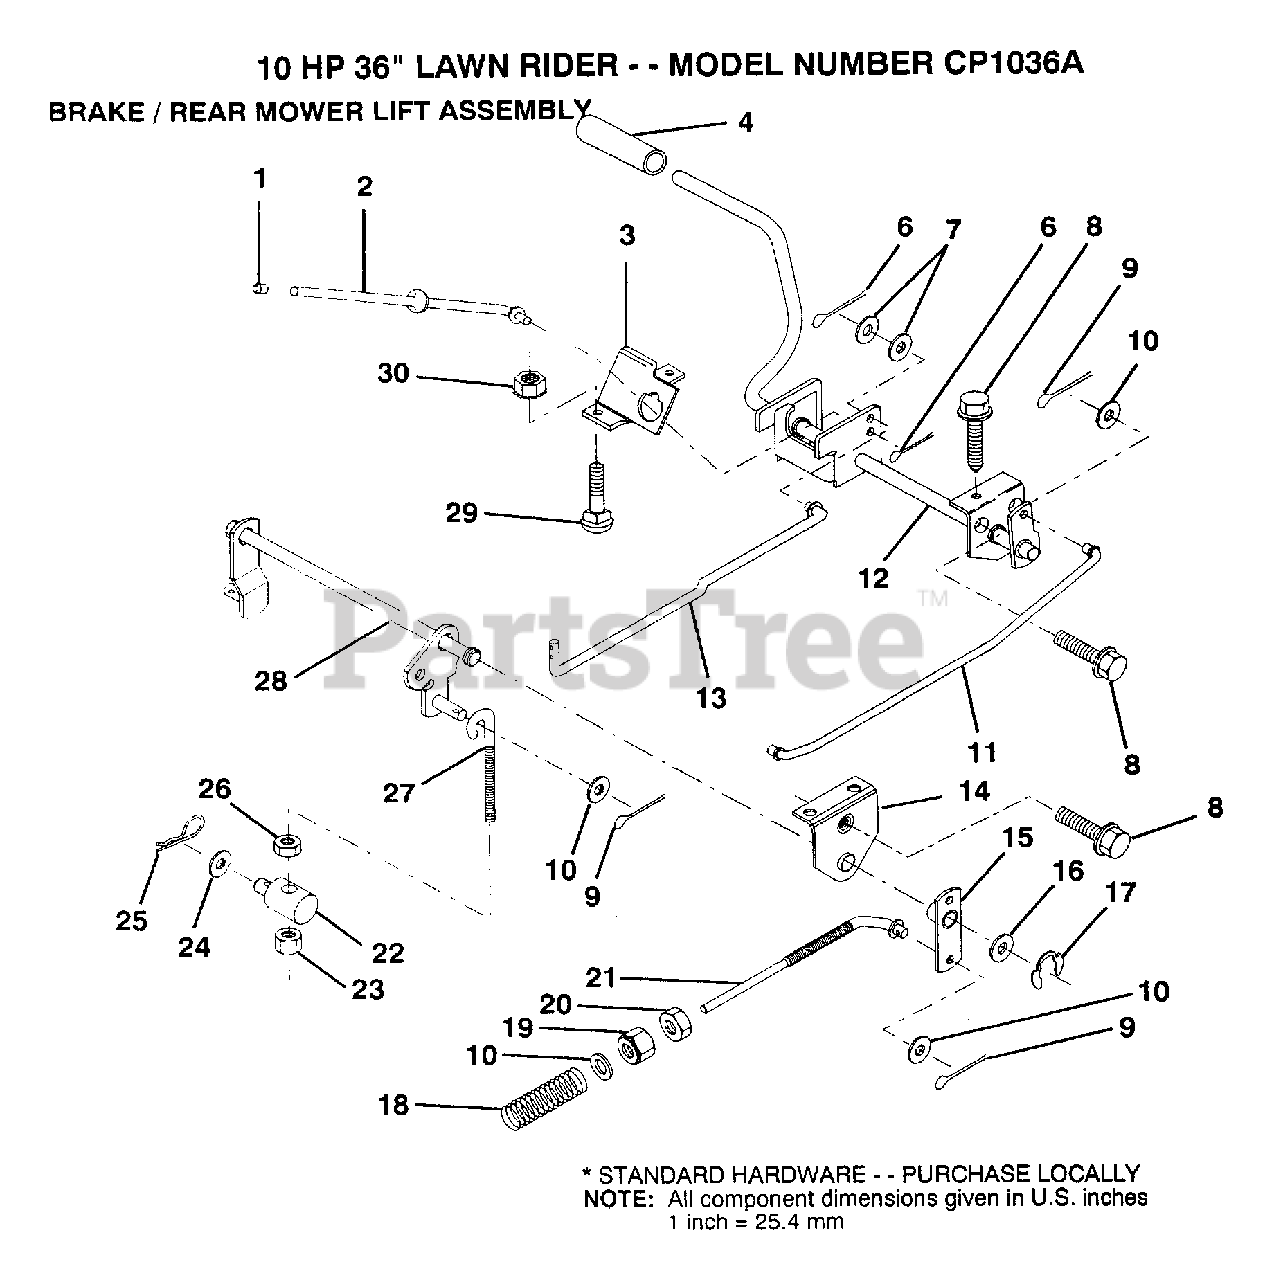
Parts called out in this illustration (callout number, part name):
1	PLUNGER CAP T
2	"ROD,PARK BRAKE"
3	"BRKT,PARK BRAKE"
4	FOOT PEDAL COVER
7	WASHER
8	SCREW LT
9	COTTER PIN
10	WASHER
13	"ROD,CLUTCH"
14	"BRKT,LIFT SHAFT"
15	PVT BRAKE ARM ASM
16	WASHER T
17	KLIP RING
18	SPRING ROD LT
20	NUT
24	WASHER
25	SPRING.RETAINER
26	LOCKNUT
27	"LINK, MOWER REAR"
